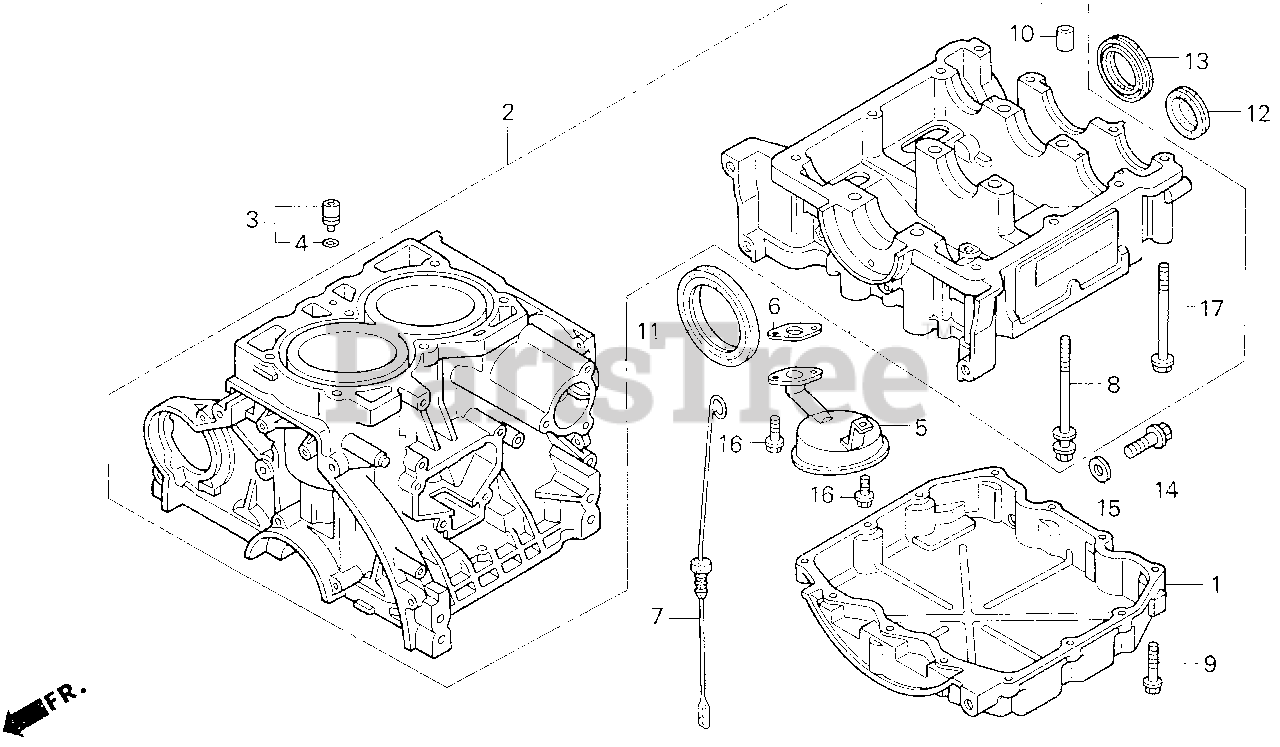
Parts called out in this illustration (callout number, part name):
2	BLOCK ASSY., CYLINDER
3	ORIFICE ASSY., OIL PASSAGE
4	O-RING (4.8X1.9)
5	STRAINER, OIL
6	GASKET, OIL STRAINER
7	DIPSTICK, OIL
8	BOLT-WASHER (10X105)
9	BOLT, FLANGE (6X28)
10	PIN, DOWEL (13X20)
11	OIL SEAL (65X88X12)
12	PLUG, SEALING (42X7)
13	OIL SEAL (35X50X8)
14	BOLT, DRAIN PLUG (12MM)
15	WASHER, DRAIN PLUG (12MM)
16	BOLT, FLANGE (6X18)
17	BOLT, FLANGE (8X85)
